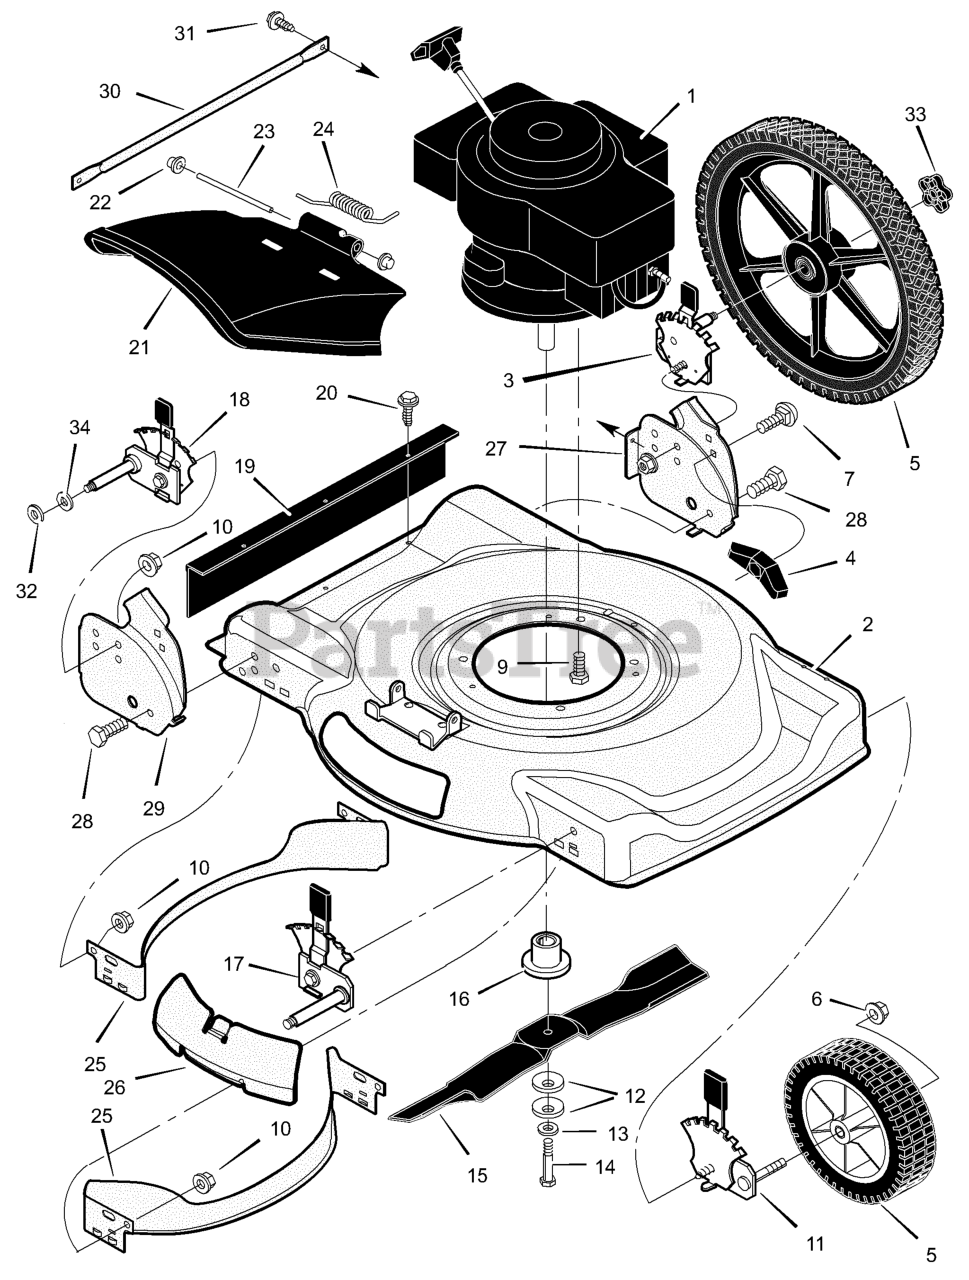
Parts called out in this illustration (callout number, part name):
1	Engine
2	Housing
3	Height Adjuster, Left Rear
5	Wheel and Tire-Front
5	Wheel and Tire-Rear
6	Locknut, Flange
7	Bolt, Carriage
9	Bolt, Engine
10	Nut
11	Height Adjuster, Left Front
12	Washer, Belleville
14	Bolt, Hex
16	Adapter, Blade
17	Height Adjuster, Right Front
18	Height Adjuster, Right Rear
19	Guard, Rear
21	Deflector, Chute
22	Push-On Cap
23	Pin, Pivot
26	Plate, Mulcher
27	Bracket, Left Handle
28	Bolt, Hex
29	Bracket, Right Handle
33	Knob, Axle
34	Washer, Spring
